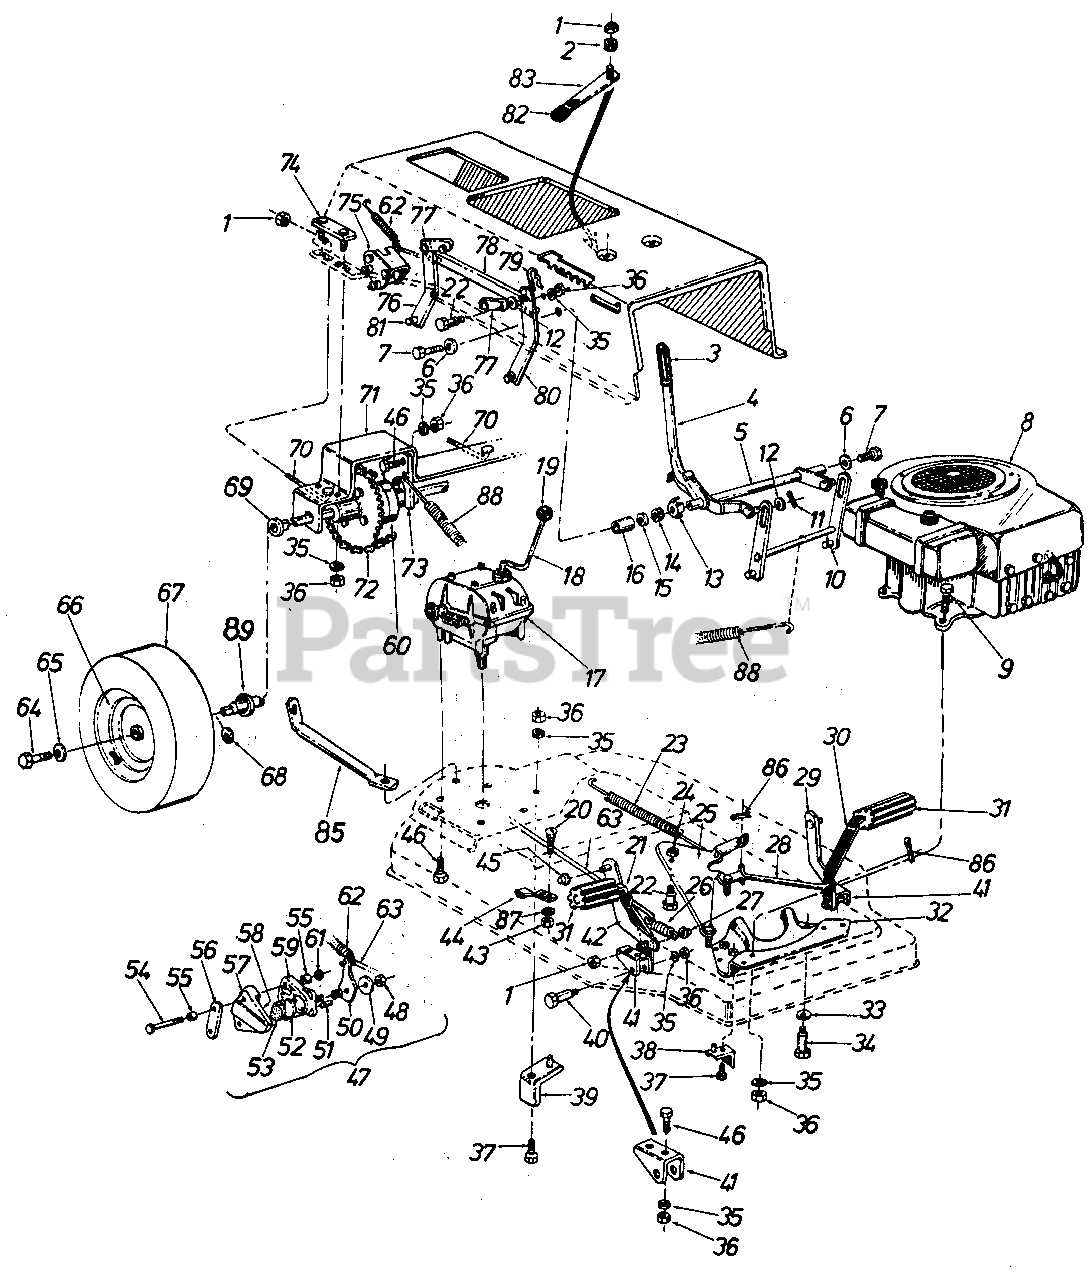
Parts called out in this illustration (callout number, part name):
1	Hex Ins. L-Nut 5/16-18 Thd.
2	Rubber Wash. .33 I.D. x .87
3	Grip Finger-Black
4	Lift Handle-R.H.
5	Lift Handle Brkt. Ass'y.
6	Belleville Wash. .40 I.D. x 1.13 O.D.
7	Hex Bolt 3/8-16 x .75" Lg.
8	Engine
9	Hex Bolt 5/16-18 x 1.50" Lg.
10	Lockout Link Ass'y.
11	Cotter Pin 1/8" Dia. x 1.00"
12	Fl-Wash. .531 I.D. x .93 O.D.
13	Handle Pivot Brkt.
14	Rubber Wash.
15	Flat-Wash .
16	Spacer .632 I.D. x .88 O.D.
17	Three Speed Trans.-Comp.
18	Shift Lever
19	Ball Knob
20	Carr. Bolt 1/4-20 x .62" Lg.
21	Brake Pedal Ass'y.
22	Shld. Scr. .431 Dia. x .18"
23	Spring (Idler) .75 O.D. x 11.0" Lg.
24	Hex Ins. L-Nut 3/8-24 Thd.
25	Idler Brkt. Ass'y.
26	Brake Spring
27	Push Nut 3/8" Dia. Rod
28	Clutch Rod
29	Clutch Lockout Lever Ass'y.
30	Clutch Pedal Ass'y.
31	Foot Pad
34	Shld. Bolt .498 Dia. x 3.00"
35	L-Wash. 5/16" Scr.
36	Hex Nut 5/16-18 Thd.*
37	Hex Sems Scr. 5/16-18 x .62" Lg.*
38	Belt Keeper Ass'y.
39	Belt Keeper Ass'y.
40	Shld. Bolt .498 Dia. x 1.450"
41	Pedal "U" Brkt. Ass'y.
42	Parking Brake Lever Ass'y.
43	Hex Nut 1/4-20 Thd.
44	Blade Brake Ass'y.
45	Push Cap .250 Dia.
46	Hex Sems Scr. 5/16-18 x .75" Lg.
47	Disc Brake Ass'y.-Comp.
48	Hex Lock Nut
49	Washer
50	Cam Lever
51	Push Pin
52	Disc Backup
53	Friction Pad 1.110" Dia. x .472 Thk.
54	Hex Bolt 5/16-18 x 2.75" Lg
55	Spacer for Disc Brake .322 I.D. x .38" Lg.
56	Brake Plate
57	Casting-Carrier Side
58	Friction Pad 1.110" Dia. x .245 Thk.
59	Casting-Cam Side
60	Differential Ass'y. Comp.
61	Hex Cent. L-Nut 5/16-18 Thd.
62	Spring .380 O.D. x 8.25n Lg.
63	Brake Rod .250 Dia. x 24.12" Lg.
64	Hex Scr. w/Lock 5/16-24 x .750" Lg.
65	Bell-Wash. .345" I.D. x .88"
66	Rear Wheel-Rim Ass'y.
67	Rear Wheel-Tire Only
68	Fl-Wash.
69	Flange Brg.
70	Chain Adj. Link 5/16-18 Thd
71	RearAxle Brkt.
72	#41 Chain 1/2" Pitch x 65 Links
73	Rear Axle Plate
74	Axle Bolt Plate Ass'y.
75	Disc Brake Brkt. Ass'y.
76	Deck Link
77	Pivot Link Ass'y.
78	Connecting Lift Brkt.
79	Int. Cotter Pin 1/2" Dia.
80	Deck Link Ass'y.
81	Lift Brkt. Pin
82	Ht. Adj. Knob
83	Handle Stop Brkt. Ass'y.
85	Reinforcement Brkt.
86	Cot-Pin 1/8n Dia. x 3/4" Lg.
87	L-Wash. 1/4" I.D.
88	Spring 14.25n Lg.
89	Spacer .758 I.D. x .99 O.D.
